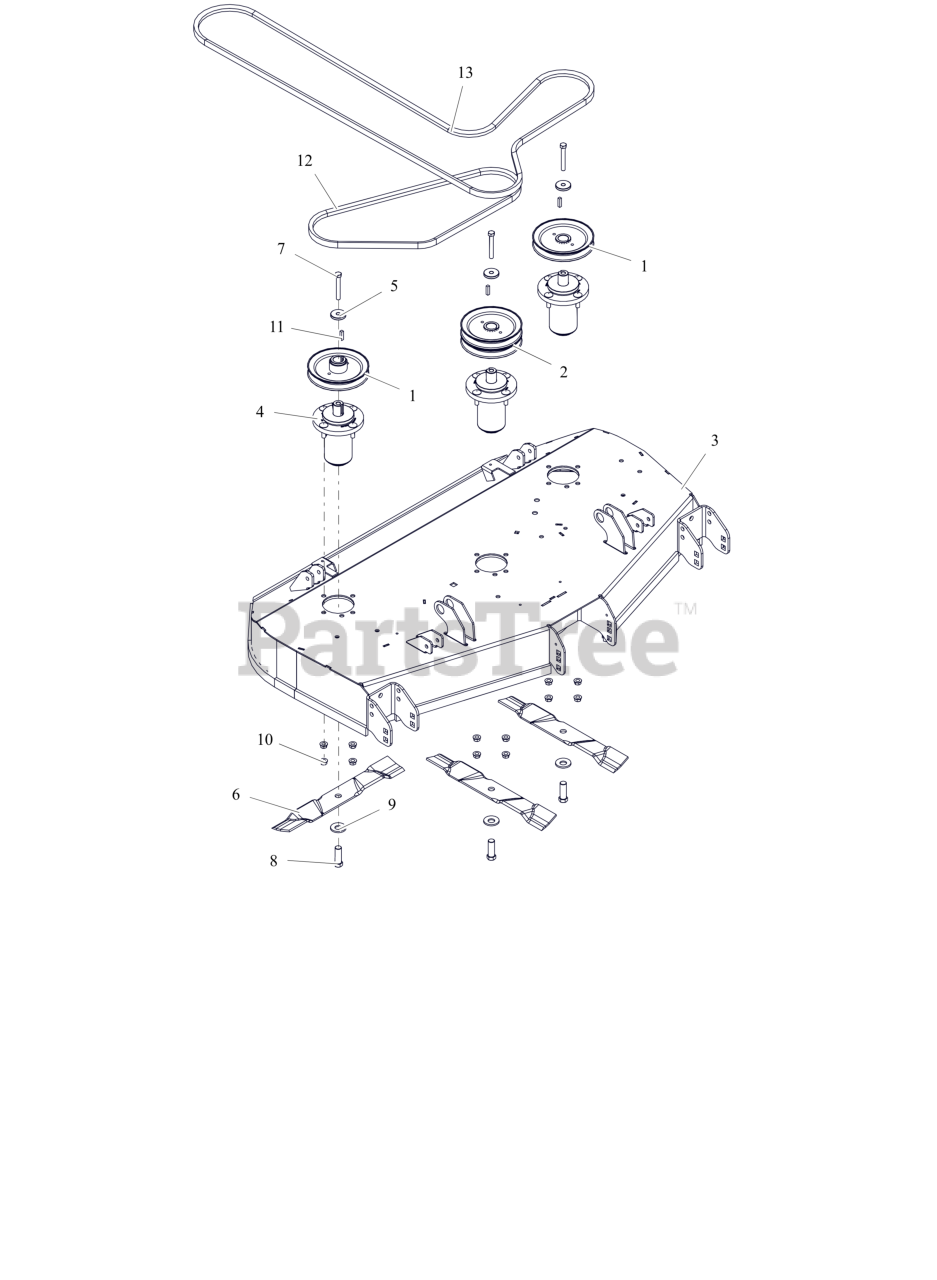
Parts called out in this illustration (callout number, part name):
1	PULLEY, SINGLE-1"ID X 6" OD
2	PULLEY, DOUBLE
3	WLDMT, DECK 48" REAR DISCHARGE
4	ASM, MAINT FREE ALUM SPINDLE
5	RETAINER, SHEAVE
6	BLADE, MULCH - 16.25"
7	BLT, HEX .38-16X2.75 G8 ZCC
8	BLT, HEX .62-18X1.75 G8 ZCC
9	WSHR-BLVL .669X1.535X.138
10	NUT-LK-CTR-FLG .375-16 GF ZCC
11	KEY, SQ .25X.25X1.00 RC 40-50
12	V-BELT, B-COGGED
13	V-BELT, HB SECTION
